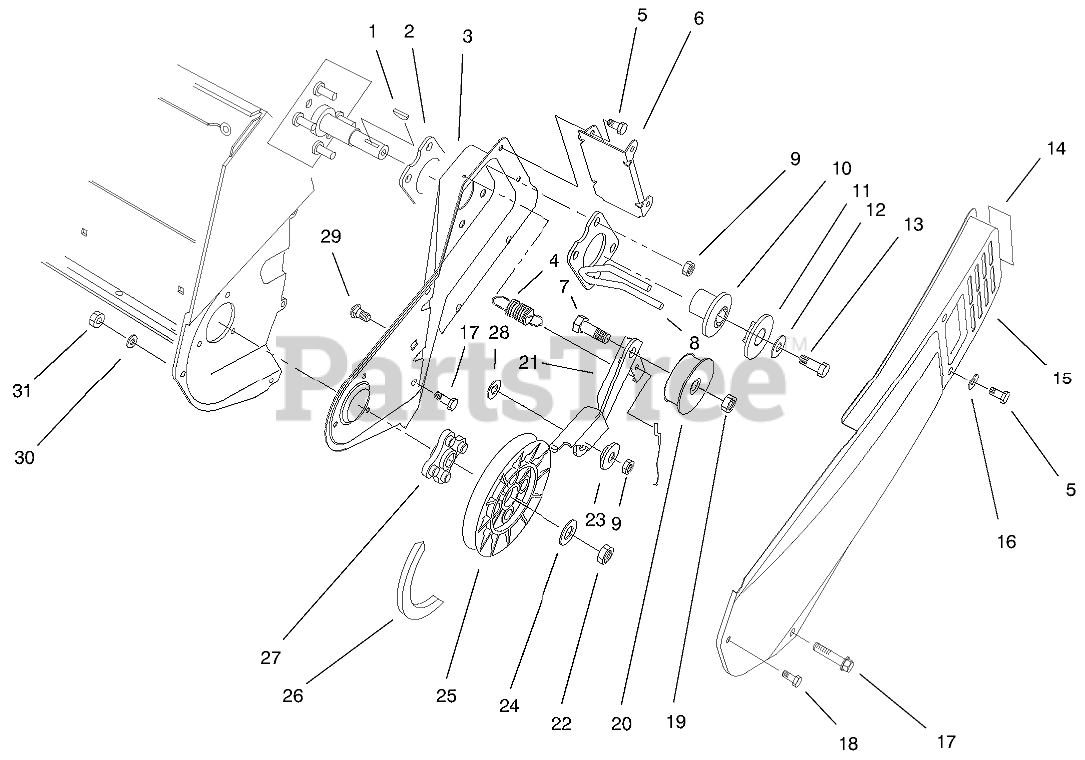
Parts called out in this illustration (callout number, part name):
1	KEY-WOODRUFF
2	PLATE-ENGINE
3	SIDEPLATE-LH
4	SPRING-BRAKE
5	SCREW-HWH
6	BRACKET-COVER, BELT
7	SCREW-HH
8	GUIDE-BELT
9	NUT-LOCK, NI
10	Hub-HALF SHEAVE
11	CAP-HALF SHEAVE
12	WASHER-FLAT
13	SCREW-HH
14	DECAL-HOT
15	COVER-BELT
16	WASHER-FLAT
17	SCREW-PLASTIC
19	NUT-LOCK, NI
20	PULLEY-IDLER
21	ARM-BRAKE
22	NUT-LOCK, NI
23	BUSHING-IDLER
24	WASHER-FLAT
25	PULLEY-DRIVEN
26	V BELT
28	WASHER
29	SCREW-CARR
30	WASHER-FLAT
31	NUT-LOCK, NI
